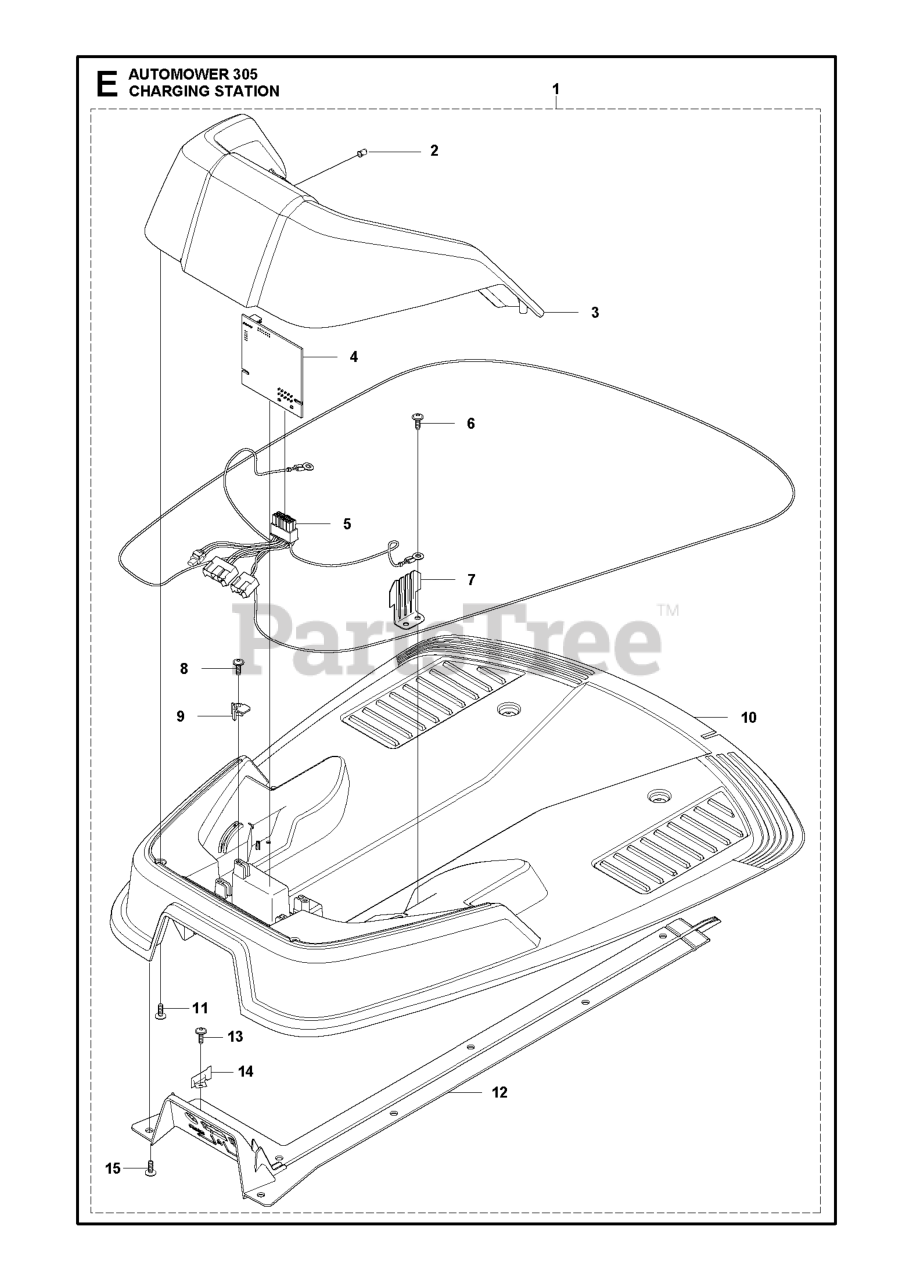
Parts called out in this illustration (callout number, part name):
2	LENS
6	SCREW 14MM
7	CONTACT CHARGER STATION CONTAC
8	SCREW 14MM
11	SCREW 14MM
13	SCREW 14MM
15	SCREW 14MM
